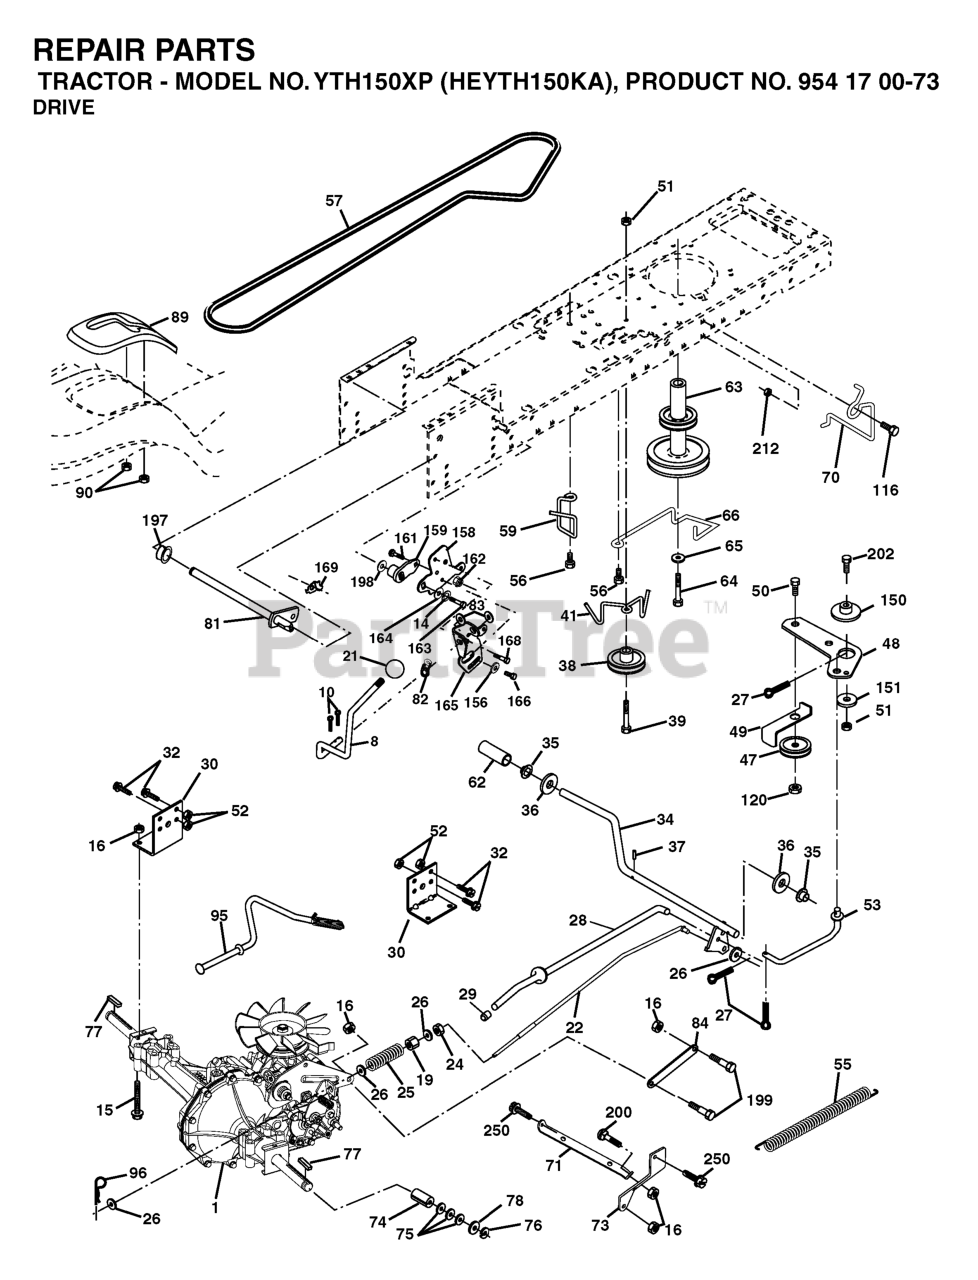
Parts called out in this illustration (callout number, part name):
8	ROD SHIFT FENDER ADJUST STLT
10	PIN COTTER
14	LOCKWASHER
15	BOLT HEX 5/16-18 GR 5
16	NUT.71038.31-18.HEX.NYLOCK
19	NUT
21	KNOB.DUCKHEAD.1/2
22	ROD BRAKE HYDRO
24	NUT
25	SPRING ROD LT
26	WASHER
27	COTTER PIN
28	ROD, PARKING BRAKE
29	PLUNGER CAP
30	BRKT, TRNSXLE MNT 20"
32	BOLT
34	SHAFT, FOOT PEDAL
35	BEARING.NYLON
37	DRIVE PIN
38	PULLEY IDLER COMPOSITE
39	BOLT
41	KEEPER, BELT IDLER
47	IDLER PULLEY
48	BELLCRANK, CLUTCH
49	RETAIN BELT
50	BOLT.3/8-16X1.50
52	LOCKNUT
53	LINK, CLUTCH LT
55	SPRING, RETURN LT
56	SCREW.3/8-16
57	DRIVE BELT, LTH & YTH TRACTORS
59	KEEPER, BELT CENTER
61	SCREW 3/8-16X.875
62	COVER, PEDAL (1 2)
64	BOLT
65	LOCKWASHER
66	KEEPER BELT ENGINE
71	STRAP TORQUE LH HYDRO
73	STRAP TORQUE RH HYDRO
74	SPACER AXLE
77	SQUARE KEY
81	SHAFT ASM CROSS TAPERED
82	SHIFT SPRING
83	WASHER
84	LINK TRANSAXLE
89	SHIFT CONSOLE
90	NUT.PUSH.3/16
95	CONTROL ASM. BYPASS HYDRO
96	RETAINER M
116	BOLT D
120	NUT LOCK FLG 3/8-16 UNC
150	SPACER, RETAINER
151	WASHER 12/32X2X10GA
156	WASHER.SRRTD.5/16
158	BRACKET
159	HUB
161	BOLT
162	NUT.CROWNLOCK.1/4
164	Washer 5/8 x .281 x 10 Ga.
165	RP BRACKET
168	BOLT.SHOULDER.5/16-18X
169	PLATE.FASTENING.CROSS.SHAFT
197	NYLINER SNAP 5/8" ID
198	WASHER.NYL.7/8IDX.105"HYD CR
199	BOLT SHOULDER 5/16-18 UNC
212	NUT
250	SCREW 3/8-16X3/4
